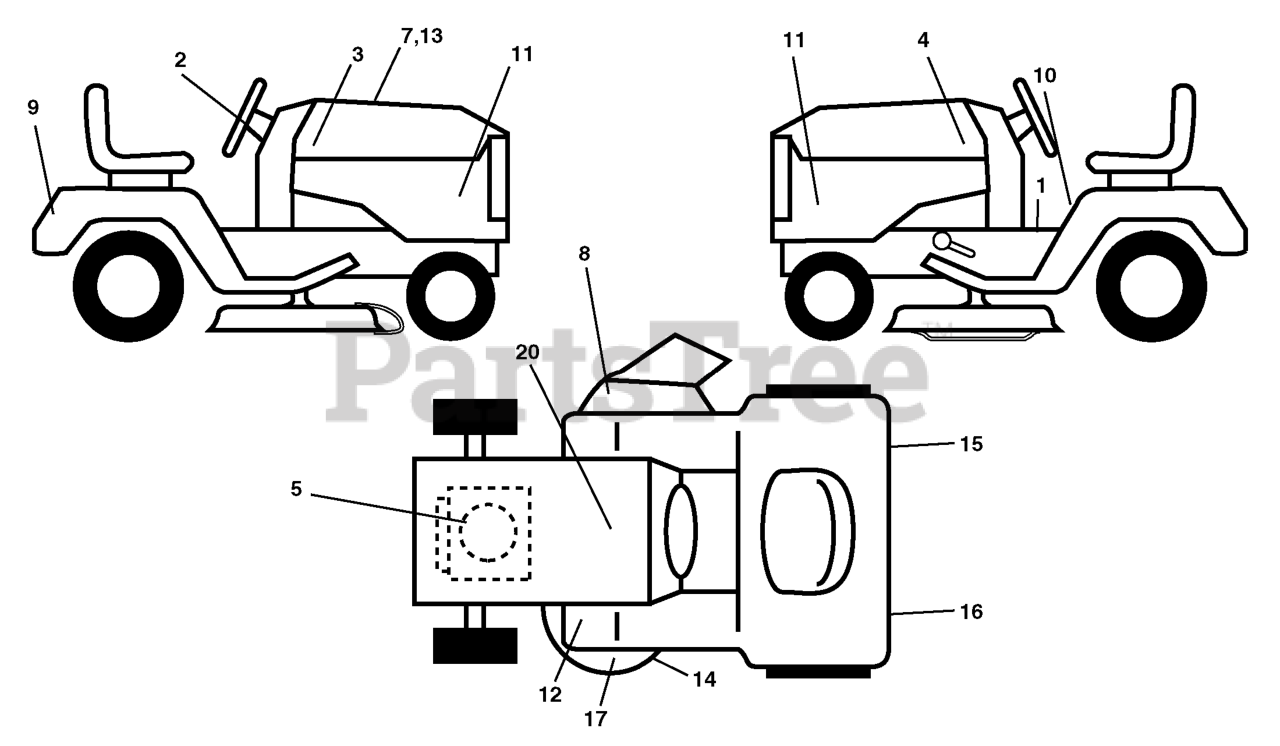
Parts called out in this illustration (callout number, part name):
2	DECAL.WHEEL.STEERING.HUSQ.PERM
3	HOOD DECAL
4	HOOD DECAL
5	DECAL ENGINE
7	DECAL, 'REPLACEMENT PARTS'
8	DECAL.WARN.KEEP.HAND.AWAY
9	DECAL, FENDER
10	DECAL FENDER DANGER
11	DECAL HOOD SIDES
12	DECAL CLUTCH/BRAKE
13	DECAL HOOD CUST. RESP.
14	DECAL V-BELT SCHEMATIC
15	DECAL RH REFLECTOR
16	DECAL REFLECTOR LH
17	DECAL, MOWER HEAVY DUTY
20	DECAL BTRY SYMBOLS
